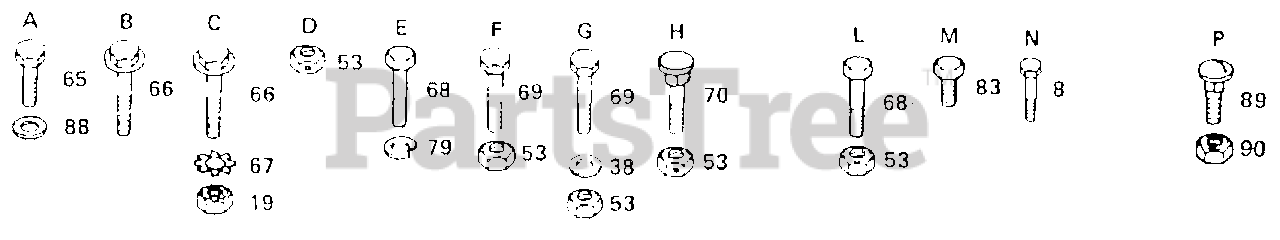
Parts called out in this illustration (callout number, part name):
19	NUT
38	WASHER
65	SCREW
66	SCREW LT
67	LOCKWASHER
69	BOLT
70	BOLT
79	LOCKWASHER
83	SCREW
88	WASHER
89	BOLT
